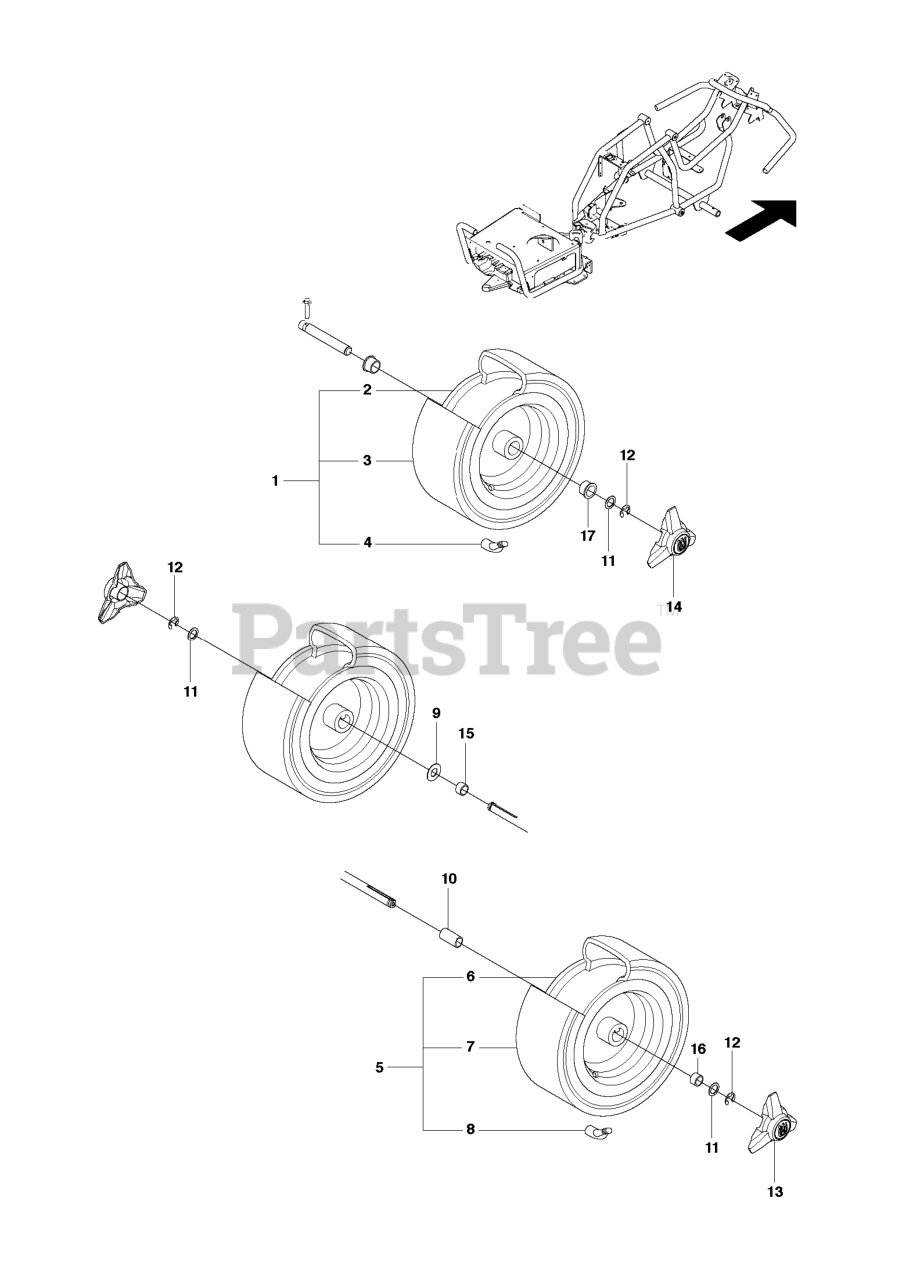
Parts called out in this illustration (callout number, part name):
4	VALVE
8	VALVE
12	RETAINING RING
